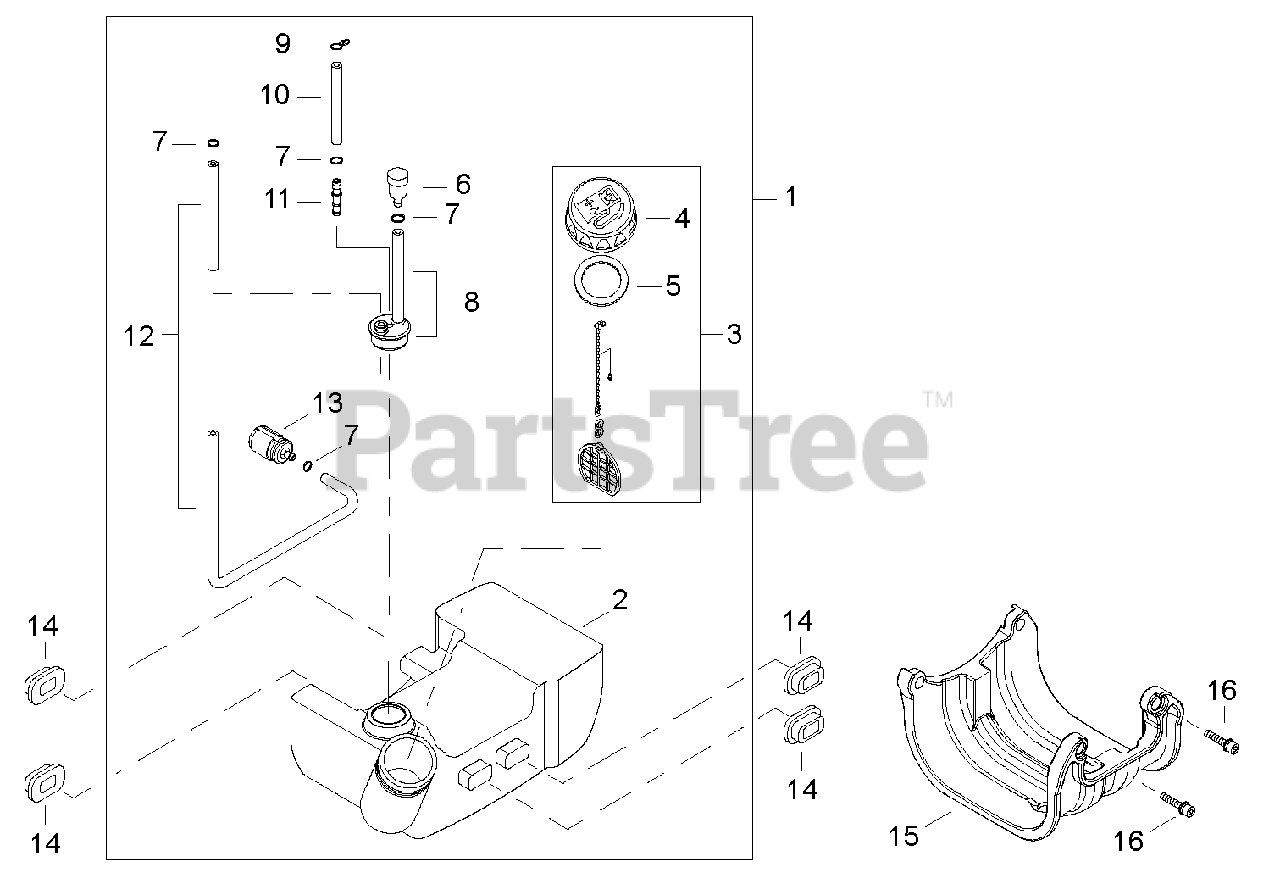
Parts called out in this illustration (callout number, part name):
1	TANK ASSY, FUEL
2	TANK, FUEL
3	CAP ASSY, FUEL
4	CAP, FUEL
5	GASKET, FUEL CAP
6	VENT ASSY
7	CLIP Ø6
8	GROMMET, FUEL W/VENT PIPE
9	CLIP, SPRING Ø5.2
10	PIPE, FUEL RETURN
11	CONNECTOR, PIPE
12	PIPE, FUEL
13	FILTER, FUEL 125-528
14	CUSHION, FUEL TANK
15	GUARD, PLASTIC FUEL TANK
16	BOLT M5×20
